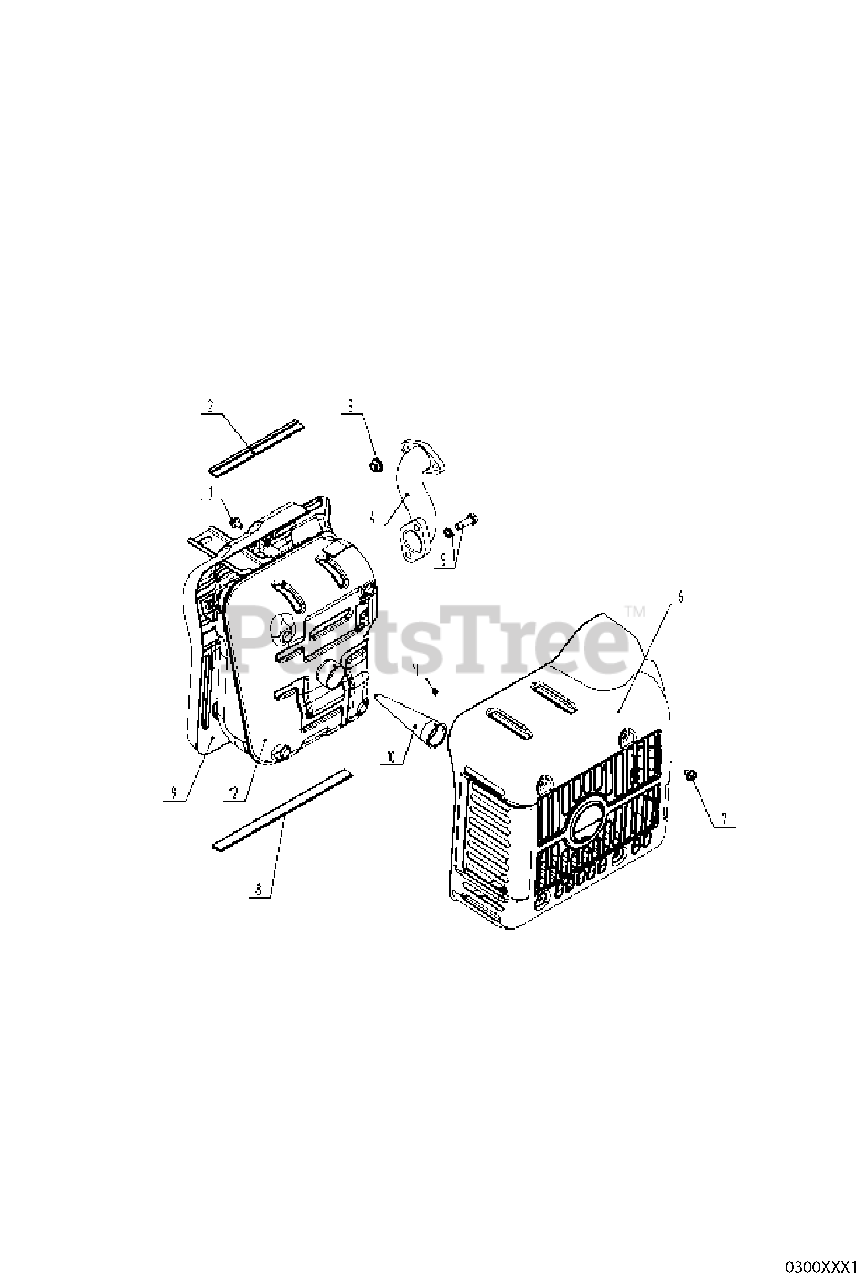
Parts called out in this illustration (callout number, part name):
1	HEXAGON BOLT M6X10
2	MUFFLER SHOCK PAD
5	SUS FLANGE BOLT M8X25
7	HEXAGON FLANGE BOLT M6X8
8	MUFFLER SHOCK PAD
10	SPARK ARRESTER
